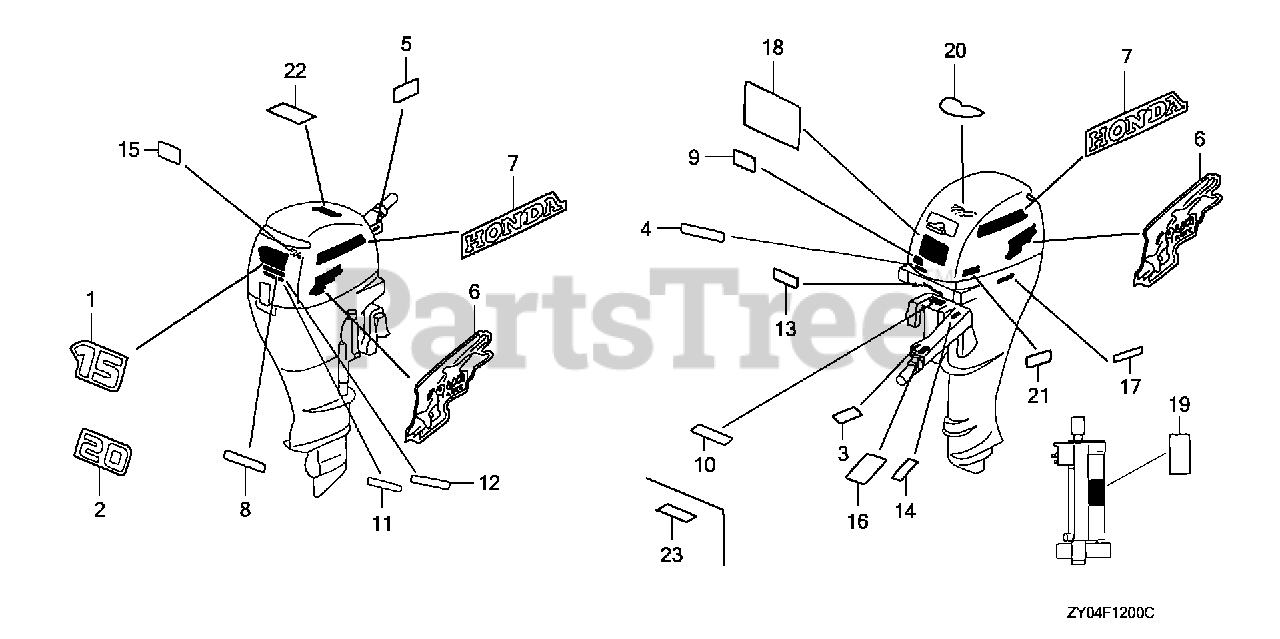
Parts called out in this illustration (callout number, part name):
2	MARK, RR. (20)
3	MARK, EMERGENCY SWITCH INDICATION
4	MARK, SPARE CLIP (ENGLISH)
5	MARK, STARTER (ENGLISH)
6	MARK, SIDE
7	MARK, SIDE STRIPE (HONDA)
8	MARK, POWER THRUST
9	MARK (E-SPEC)
12	MARK, POWER TILT
13	MARK, OIL PRESSURE
14	MARK, CHANGE
15	LABEL, OIL CAUTION (ENGLISH)
16	MARK, THROTTLE (ENGLISH)
17	LABEL, STORING CAUTION (ENGLISH)
18	LABEL, WARNING OPERATOR (ENGLISH)
20	MARK, EMERGENCY STARTER (ENGLISH)
